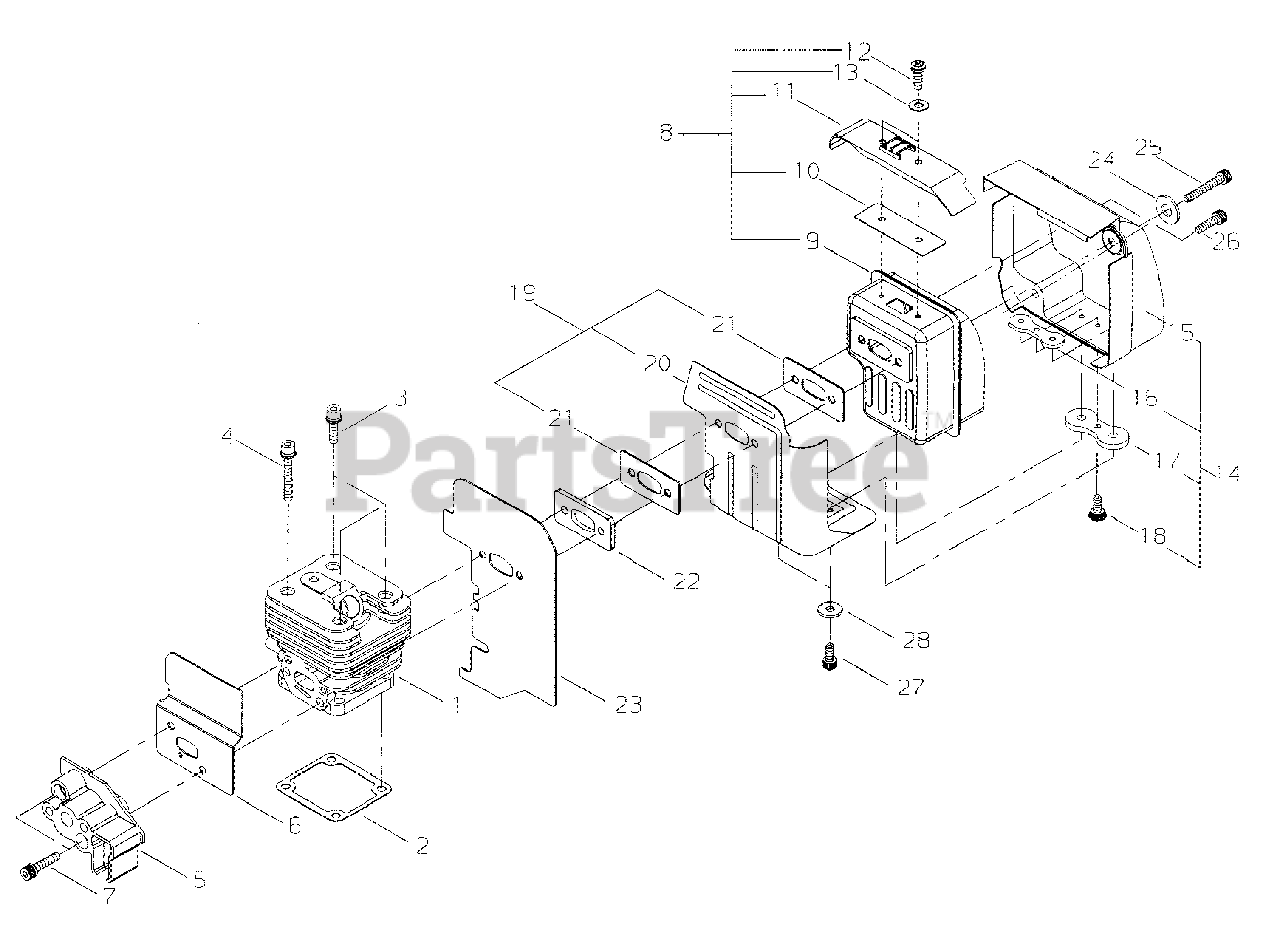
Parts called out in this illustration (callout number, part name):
1	CYLINDER
2	GASKET, CYLINDER
3	BOLT M5×16
4	BOLT M5×35
5	INSULATOR
6	HEAT SHIELD, INTAKE
7	BOLT M5×30
8	MUFFLER ASSY
9	MUFFLER
10	SCREEN, SPARK ARRESTER
11	COVER, SPARK ARRESTER
12	SCREW M4×6
13	WASHER 4 MM
14	COVER ASSY, MUFFLER
15	COVER, MUFFLER
16	PLATE
17	SPACER
18	SCREW 4×8
19	DEFLECTOR ASSY, EXHAUST HEAT
20	HEAT SHIELD, EXHAUST
21	GASKET, EXHAUST
22	SPACER
23	GASKET, MUFFLER
24	WASHER SS 5 MM
25	BOLT M5×65
26	BOLT 5×25
27	BOLT M5×10
28	WASHER Ø15ר5.2×1.6
